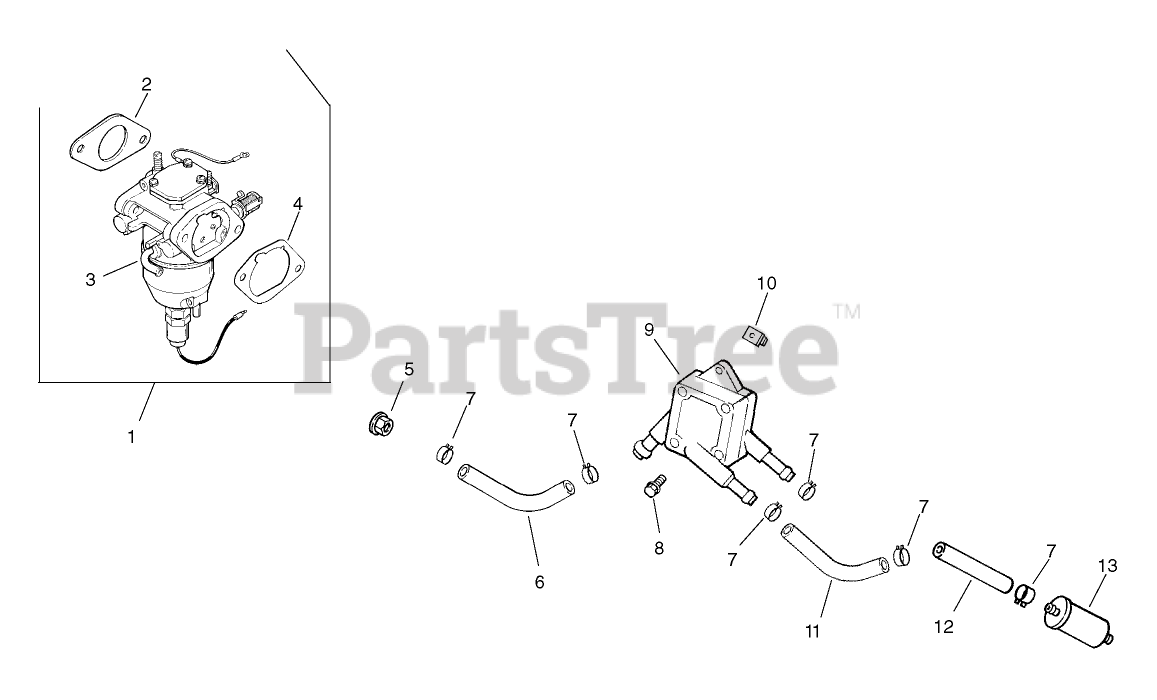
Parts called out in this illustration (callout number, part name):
1	Kit, carburetor w/gaskets (Includes 2-4)
2	Gasket-carburetor
3	Carburetor assembly (For information only not available separately)(Service with kits 24 757 36-S and 24 757 38-S)
4	GASKET-BASE, AIR CLEANER
5	NUT-FLANGE (M6X1.0)
6	Line, fuel 12"
7	CLAMP-HOSE, SPRING (1/2)
8	SCREW-TAP (M6X1.7X18)
9	PUMP-FUEL
10	Nut-Plastic
11	Line, fuel 10-1/2
12	Line-Fuel (9.5)
13	Filter, fuel
